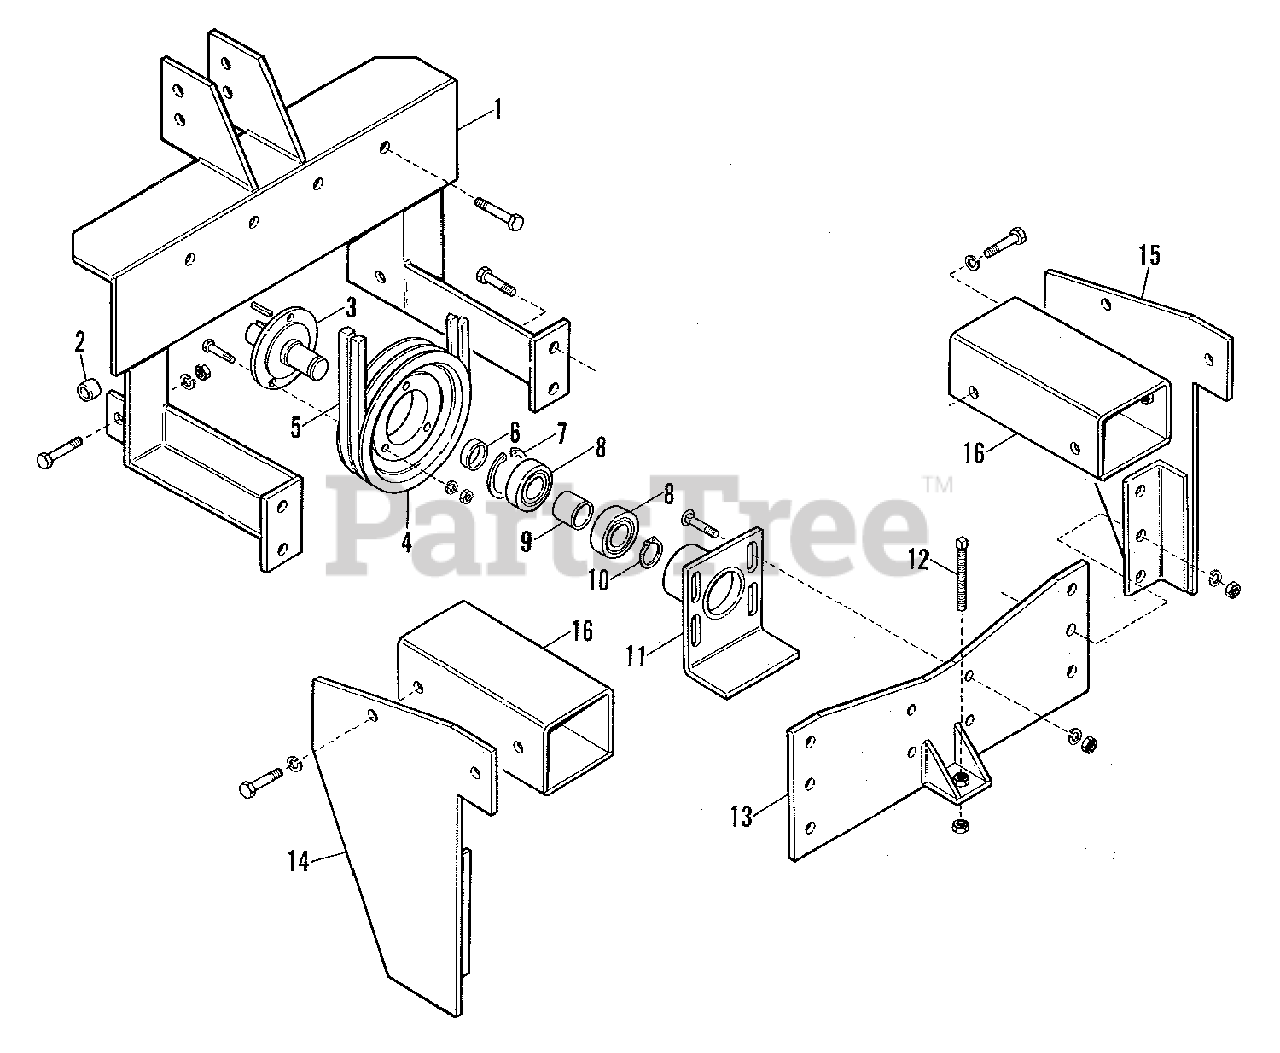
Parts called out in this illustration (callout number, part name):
1	FRAME ASSEMBLY, Drop
1	CAPSCREW, 9/16NC x 1-1/2
1	LOCKWASHER, 9/16
1	NUT, 9/16NC
1	CAPSCREW, 1/2NC x 1-3/4
1	CAPSCREW, 1/2NC x 2
1	LOCKWASHER, 1/2
3	SHAFT ASSEMBLY
3	KEY, Square, 1/4 x 1/4 x 1
3	CAPSCREW, 1/4NC x 1-1/4
3	LOCKWASHER, 1/4
4	SHEAVE (5-27/32" O.D.)
5	BELT SET, Matched, Set of 2 (38" Belt for 5030 w/Turf Tires)
5	BELT SET, Matched, Set of 2 (42" Belt for 5020 w/Ag. Or Turf Tires - 2-Wheel Only)
5	BELT SET, Matched, Set of 2 (46" Belt for 5020 w/4-Wheel Drive & for 5030 w/Ag. Tires)
6	SPACER, Shaft
7	RING, Retaining, Internal
8	BEARING, Drive Pulley Shaft
9	SPACER, Bearing
10	RING, Retaining
11	HOUSING ASSEMBLY, Bearing
11	BOLT, Carriage, 3/8NC x 1-1/4
11	LOCKWASHER, 3/8
12	SETSCREW, Square Head, Cup Point, 3/8NC x 3
13	PLATE, Mounting, PTO
14	PLATE, Frame, L.H.
14	CAPSCREW, 1/2NC x 1-1/2
14	LOCKWASHER, 1/2
15	PLATE, Frame, R.H.
15	CAPSCREW, 1/2NC x 1-1/2
15	LOCKWASHER, 1/2
16	*BOLT, Carriage, 12MM x 45MM (Use on 5020 - 2-Wheel Drive Only)
16	*LOCKWASHER, 12MM (Use on 5020 - 2-Wheel Drive Only)
16	*CAPSCREW, 1/2NC x 1-3/4 (Use on 5020 FWD)
16	*LOCKWASHER, 1/2 (Use on 5020 FWD)
16	*NUT, 1/2NC (Use on 5020 FWD)
17	SPACER, Plate
